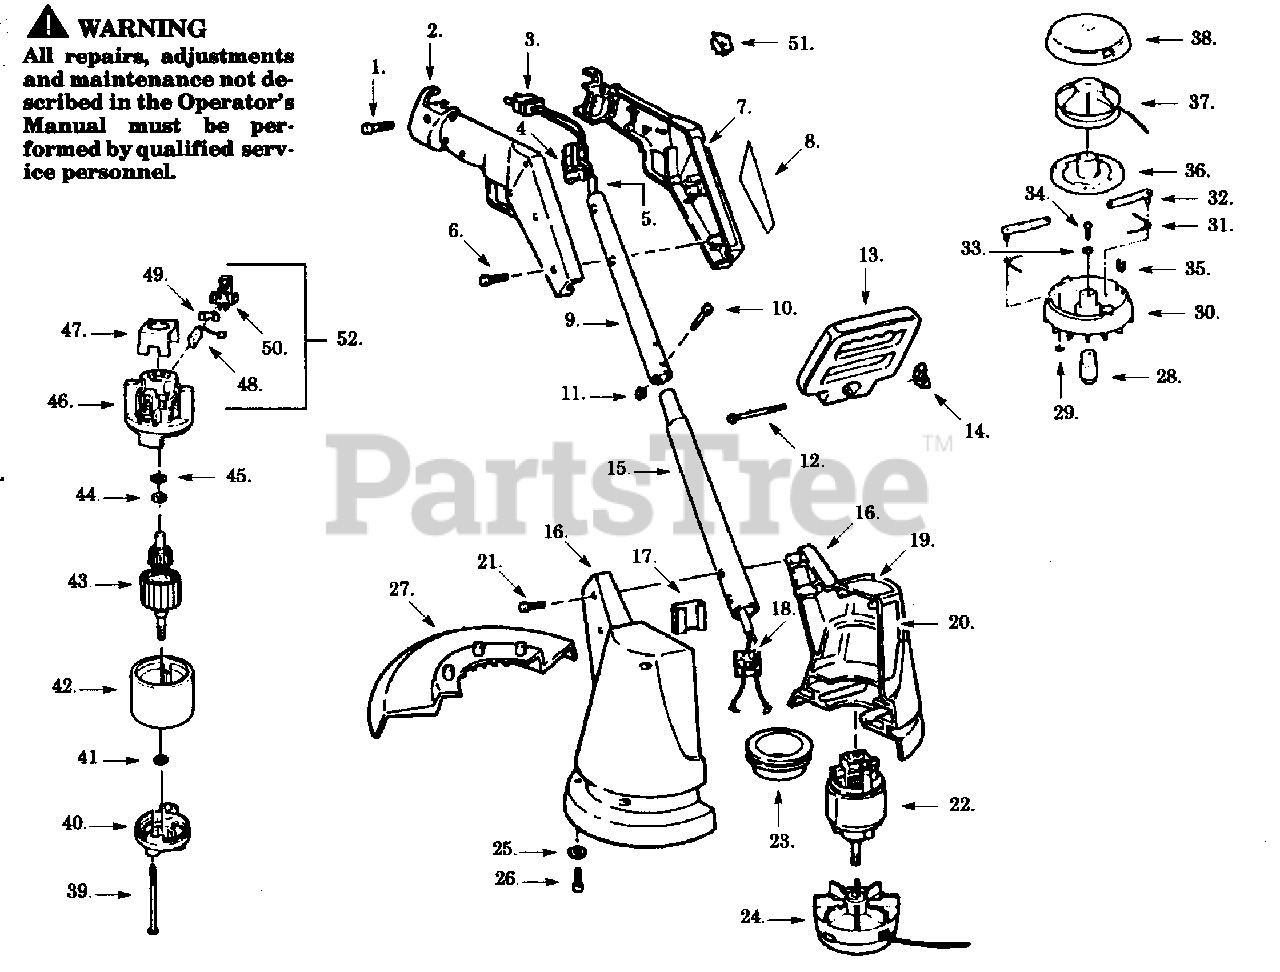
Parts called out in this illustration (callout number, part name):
2	Handle Set
4	Trigger Switch
5	Harness Ass'y.
7	Handle Label (Not a serviceable part)
8	Warning Label
9	Upper Tube
11	Stop Nut
13	Assist Handle
14	Wing Nut
15	Lower Tube
16	Housing Set
17	Insulator Shield
18	P.C. Board Ass'y.
19	Housing Label (Not a serviceable part)
20	Hsg. Front Label (Not a serviceable part)
22	Motor Ass'y.
23	Air Baffle
24	Cutting HeadAss'y.
27	Guard & Blade Ass'y.
28	Drive Adapter
29	Push Nut
30	Housing Head
35	Line Shield
37	Spool & Line
40	Endbell Ass'y. (Drive)
42	Field Ass'y.
43	Armature Ass'y.
46	Endbell Ass'y. (Brush)
47	Insulator
48	Carbon Brush
49	Brush Spring
50	Brush Holder
51	Speed Switch
52	Brush Kit (Incl. 48,49,50)
